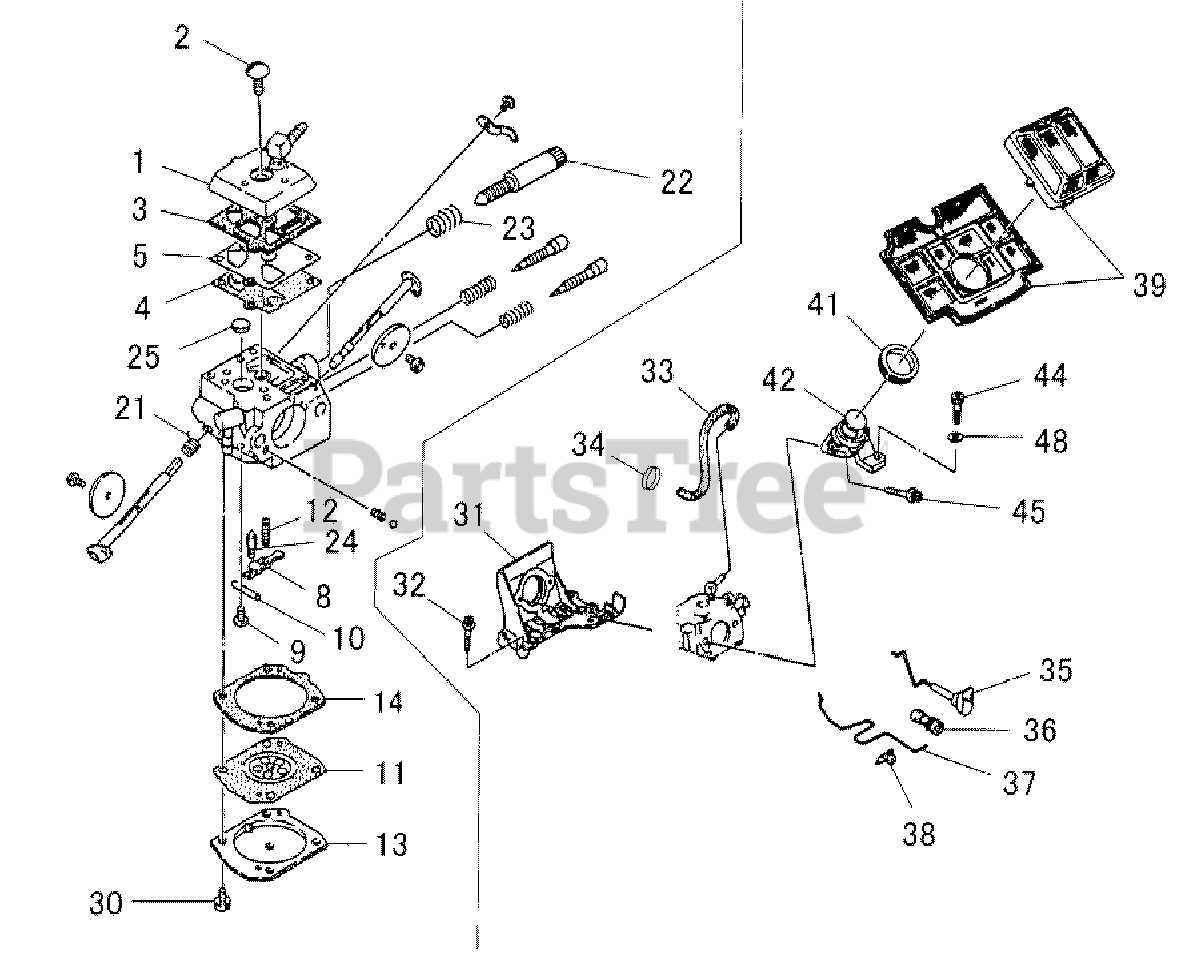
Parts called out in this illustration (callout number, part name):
1	COVER ASSY, PUMP
2	SCREW
3	GASKET, FUEL PUMP
4	DIAPHRAGM, PUMP
5	DIAPHRAGM, PUMP
8	LEVER
9	SCREW, METERING LEVER PIN
10	PIN, METERING LEVER
11	DIAPHRAGM, METERING
12	SPRING, METERING LEVER
13	COVER, METERING DIAPHRAGM
14	GASKET, METERING DIAPHRAGM
21	SPRING, THROTTLE RETURN
22	SCREW, IDLE ADJUST
23	SPRING, IDLE ADJUST
24	VALVE, INLET NEEDLE
25	SCREEN, FUEL INLET
30	SCREW
31	BRACKET
32	BOLT M4×16
32	PIPE, PULSE
33	PIPE, PULSE
34	CLIP
35	ROD, CHOKE
36	GROMMET, CHOKE
37	ROD, THROTTLE
38	GROMMET
39	AIR FILTER KIT
41	GROMMET
42	ELBOW, CARBURETOR
44	BOLT M5×18
45	BOLT M5×50
48	WASHER 5 MM
